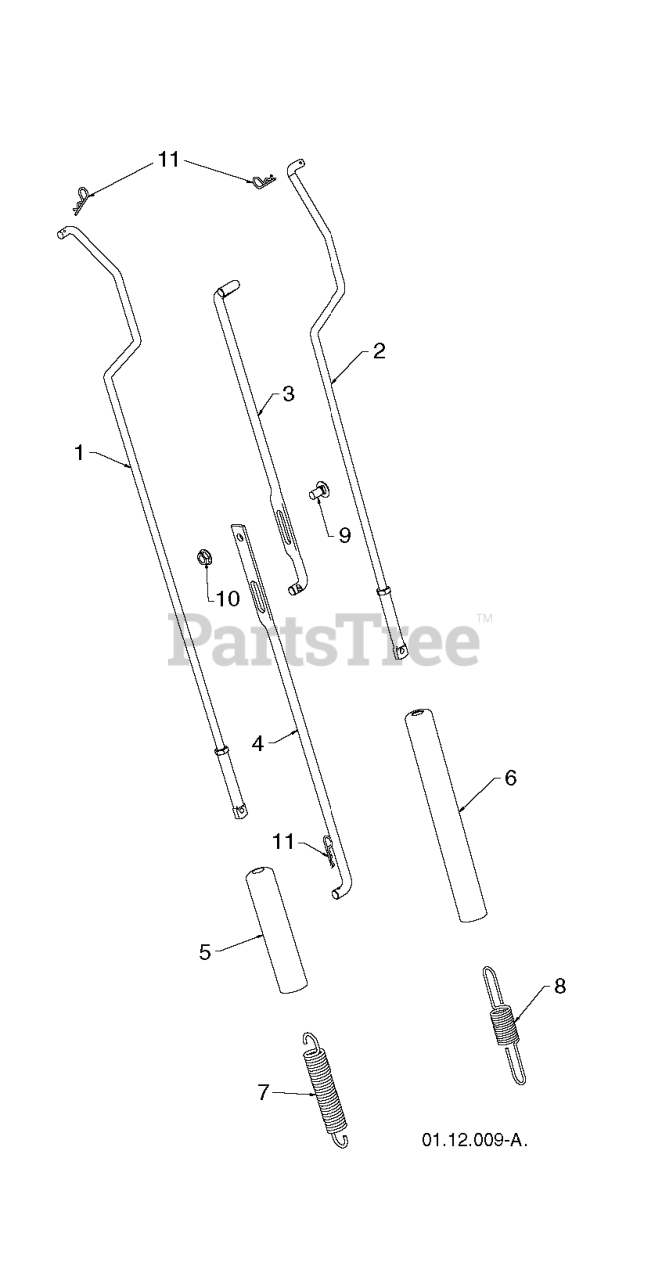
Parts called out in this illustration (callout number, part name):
1	ROD.ASM.IMPELLER.HYD
2	ROD.ASM.TRACTION.HYD.CLUTCH
3	ROD.SHIFTER.TOP.HYD.SNOW
4	ROD, LOWER, SPEED CONTROL
5	SLEEVE, SPRING
6	SLEEVE, SPRING
7	SPRING, AUGER CONTROL
8	SPRING, TRACTION DRIVE
9	BOLT
10	NUT.FLANGE.5/16
11	SPRING RETAINER
